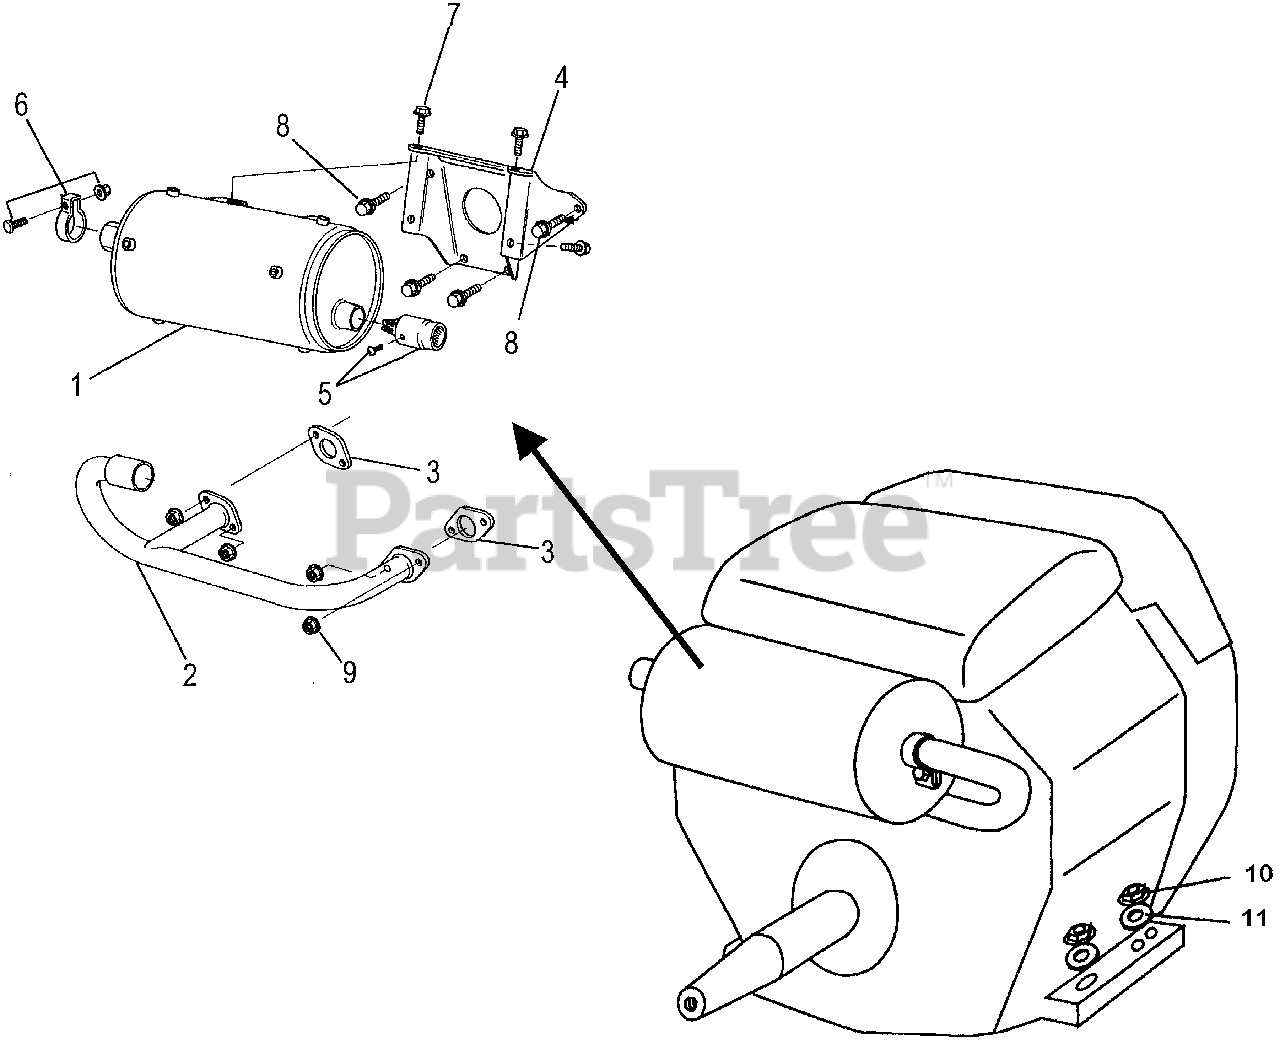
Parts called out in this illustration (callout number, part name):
1	MUFFLER (HIGH) (NOT AVAILABLE)
2	PIPE, EX. (HIGH-L)
3	GASKET, EX. PIPE (FOR SILVER MUFFLER)
4	STAY, MUFFLER (HIGH-FUTABA) (FOR SILVER MUFFLER)
5	ARRESTER, SPARK (FOR BLACK MUFFLER)
6	CLAMP, EX. PIPE
7	BOLT, FLANGE (8X16) Use from Engine SN 1000016.
8	BOLT, FLANGE (8X20) Use up to Engine SN 1609606.
9	NUT, FLANGE (8MM)
10	NUT, FLANGE (10MM)
11	WASHER, PLAIN (10MM)
